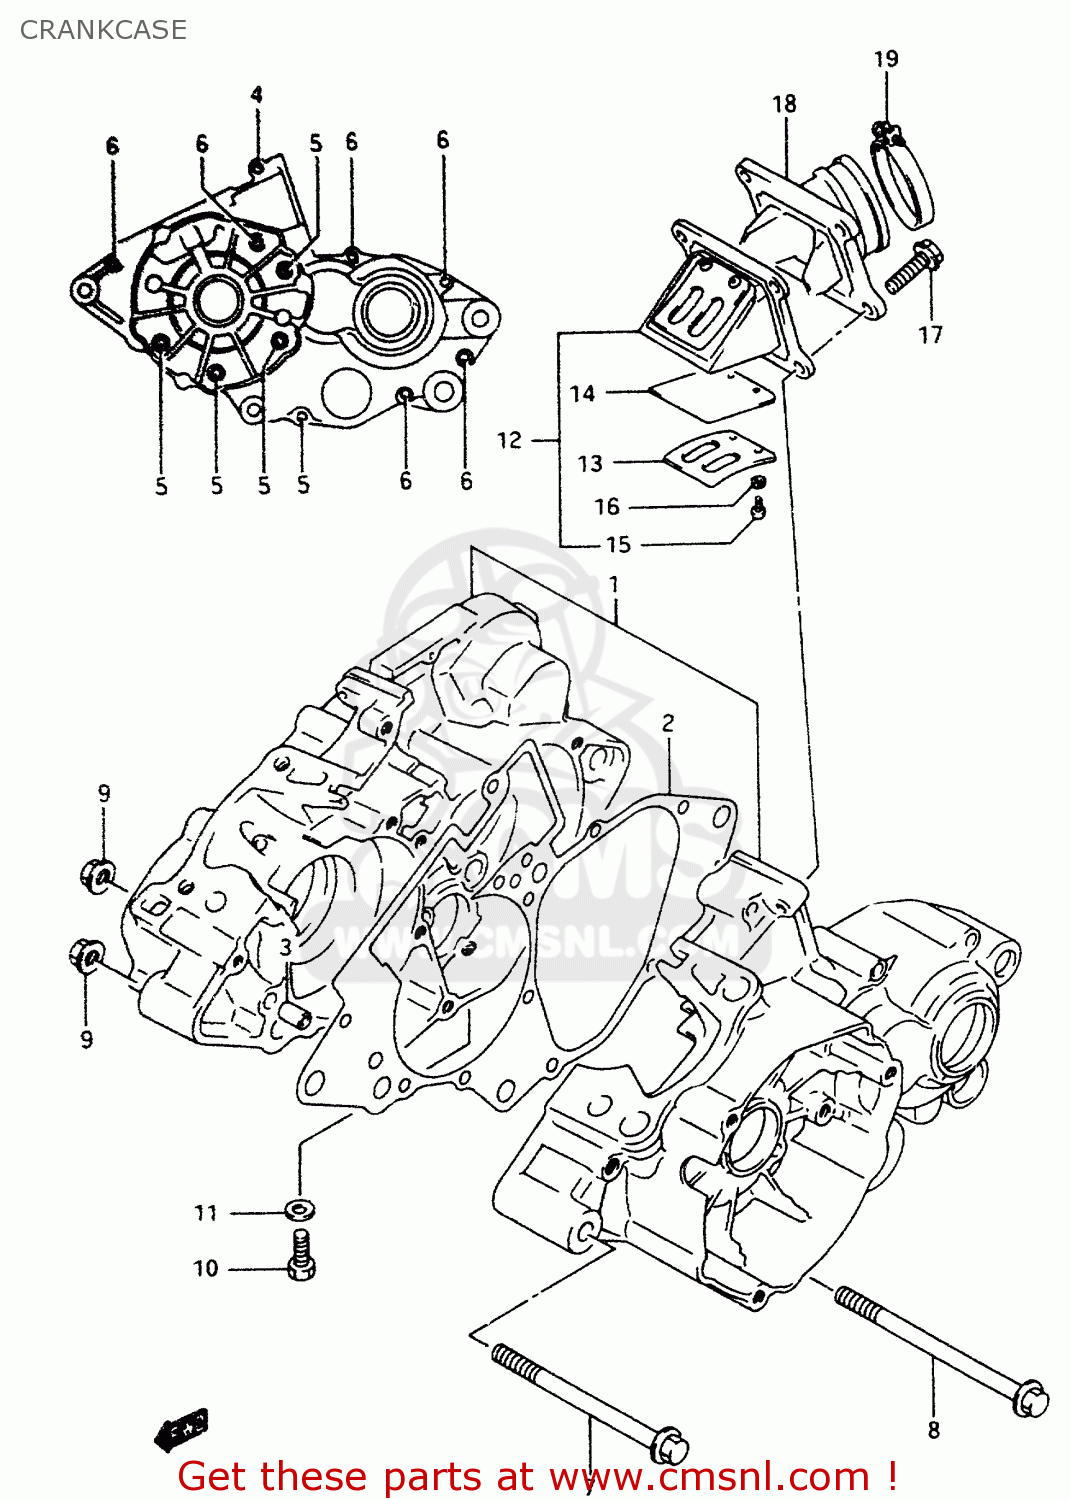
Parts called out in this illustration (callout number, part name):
1	CRANKCASE SET
2	GASKET,CRANKCASE (NAS)
3	PIN
4	BOLT
5	BOLT
6	BOLT
7	BOLT 8X92
8	BOLT(8X102)
9	NUT
10	BOLT
11	GASKET(8.2X14X1) (NAS)
12	VALVE ASSY,REED
13	STOPPER,REED VALVE
14	VALVE,REED
15	SCREW
16	WASHER,LOCK
17	SCREW
18	PIPE,INTAKE
19	CLAMP
